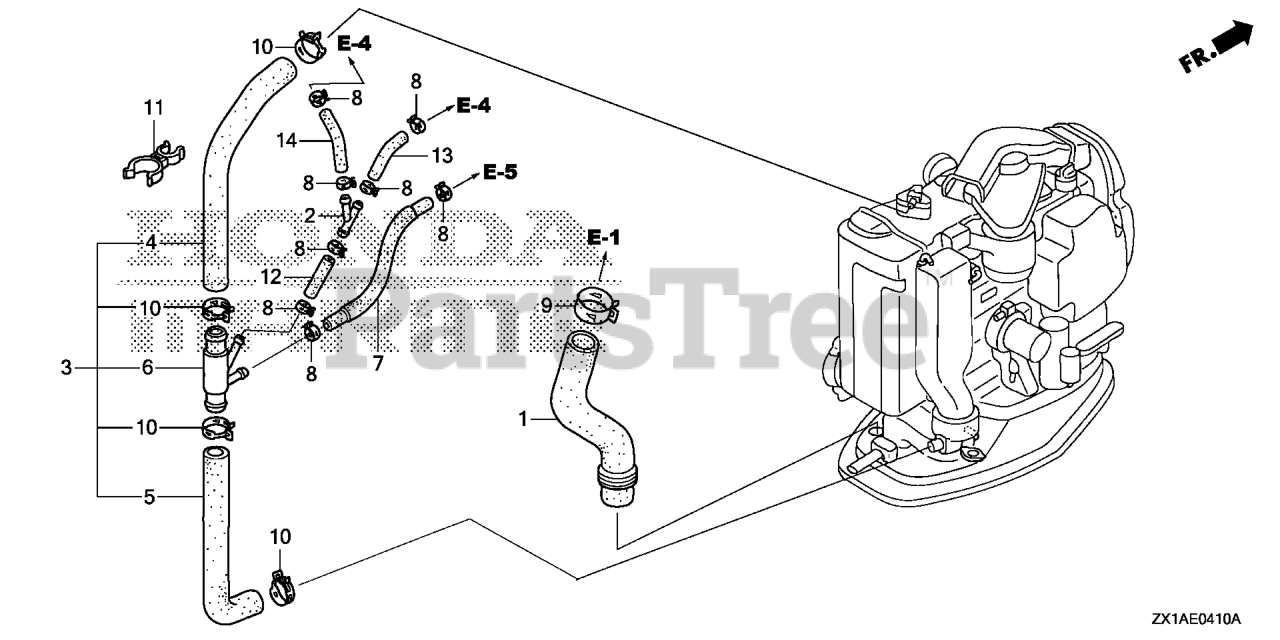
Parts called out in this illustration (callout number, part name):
2	JOINT, FUEL TUBE
3	TUBE, WATER RELIEF
4	TUBE A, WATER RELIEF
5	TUBE B, WATER RELIEF
6	JOINT, FOUR-WAY
7	TUBE E, WATER
8	CLAMP, TUBE (D10.5) (ENGINE NO.)
9	CLAMP, TUBE (D32.5)
10	CLAMP, TUBE (D25.0)
11	CLAMP, WATER TUBE
12	BULK HOSE, VACUUM (7X3000) (7X550)
13	BULK HOSE, VACUUM (7X3000) (7X550)
14	TUBE COMP, WATER
14	BULK HOSE, VACUUM (7X3000) (7X550)
